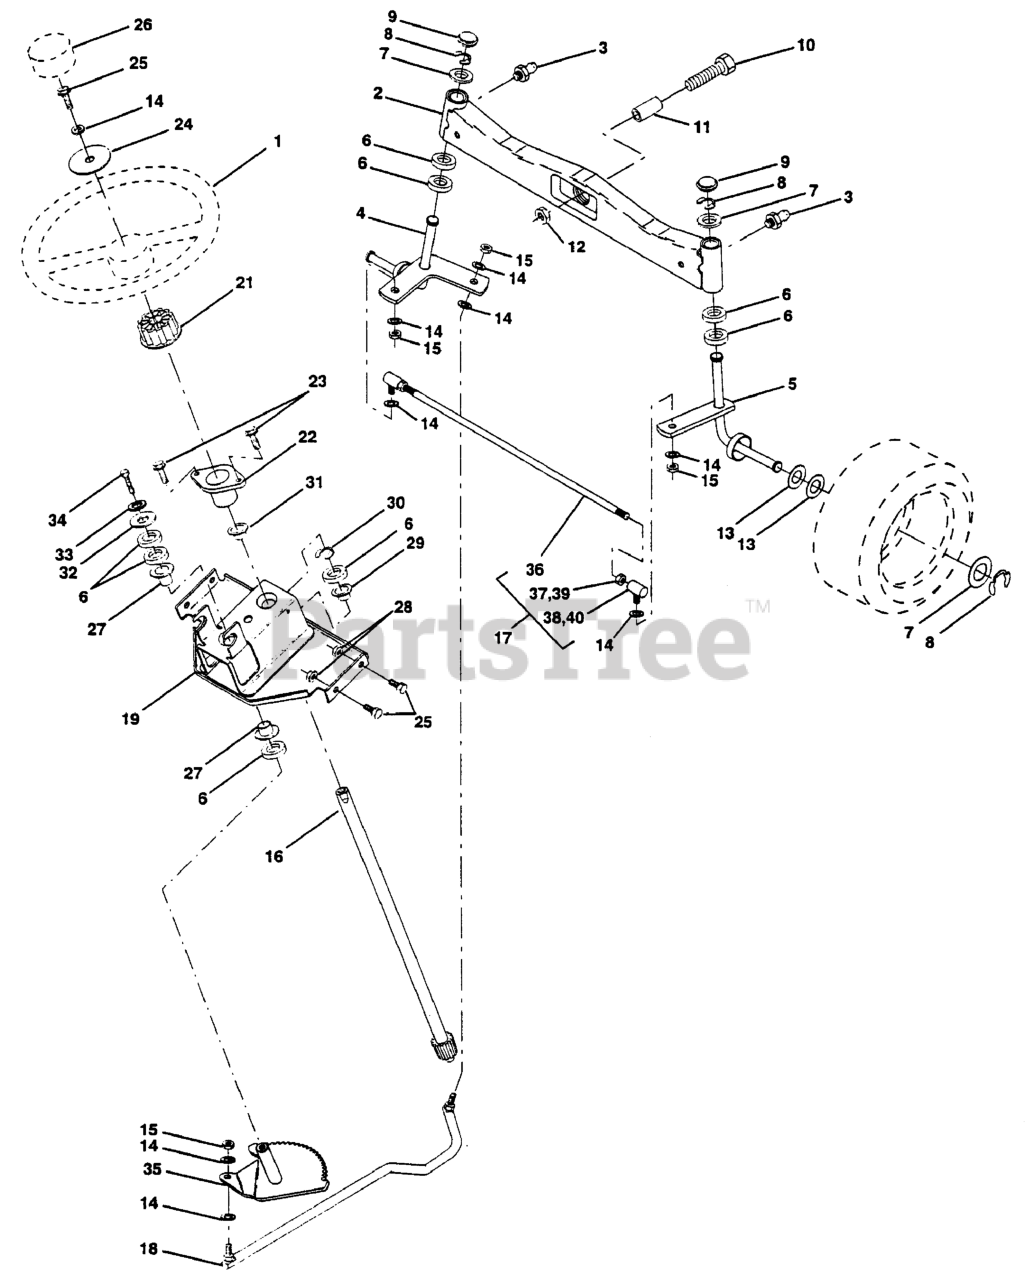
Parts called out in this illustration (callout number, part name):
1	STEERING WHEEL
2	FRONT AXLE ASSY
3	ZERK M
4	SPINDLE ASSY LH
5	SPINDLE ASSY RH
6	BEARING RACE
9	CAP.SPINDLE.BLACK
10	Bolt, Fin Hex 5/8-11 x 2-3/4
11	TUBE, PIVOT AXLE
12	NUT-LOC,FLANGE LT
14	WASHER, LOCK 3/8
15	NUT
16	SHAFT STEERING GT
17	ROD ASSY/TIE BALL
18	DRAGLINK-BALL JOINT SOLID
19	SUPPORT ARM
21	ADAPTER LT
22	BUSHING LT
23	SCREW LT
24	WASHER T
25	BOLT
26	INSERT,STR WHEEL
27	BRNG T
28	NUT
29	BEARING-FLANGE GT
30	Ring, Klip Truarc #5304-75
31	BUSHING.NYLINER.
33	WASHER.LOCK.HVY.HLCL.SPR.5/16
34	BOLT
35	GEAR.ASM.SECTOR.
36	TIE ROD
38	JOINT
